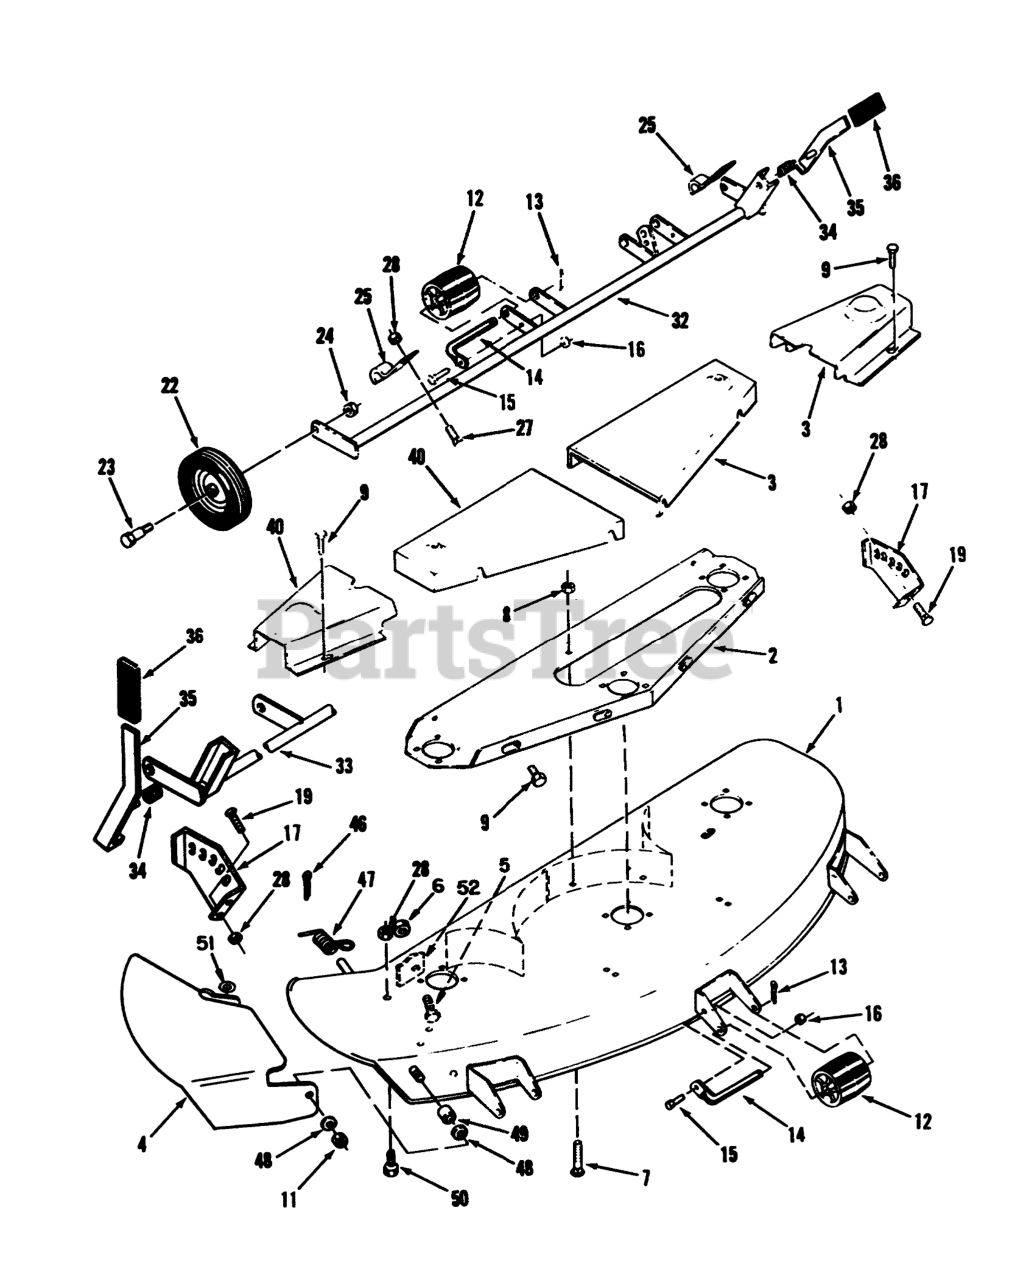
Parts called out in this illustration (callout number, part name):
1	Mower Deck 15-48SC02
2	Channel
3	Belt Cover LH
4	Chute Extension
5	SCREW-HH
6	NUT-LOCK, NI
7	BOLT-CARR
8	NUT-LOCK, NI
9	Screw
11	Nut
12	Roller
13	PIN-COTTER
14	ROLLER-SHAFT
15	SCREW-HH
16	NUT-LOCK, NI
17	Quadrant
19	BOLT-CARR
22	WHEEL
23	BOLT-SHOULDER
24	NUT-HEX
25	Clamp
27	BOLT-CARR
28	NUT-LOCK, NI
32	Support-Gage Wheel
33	Support-Gage Wheel
34	SPRING-COMPRESSION
35	Lever
40	Belt Cover RH
46	PIN-COTTER
47	Spring
48	Washer
49	BUSHING-PIVOT
50	Bolt
51	WASHER-FLAT
52	Guard-Chute
